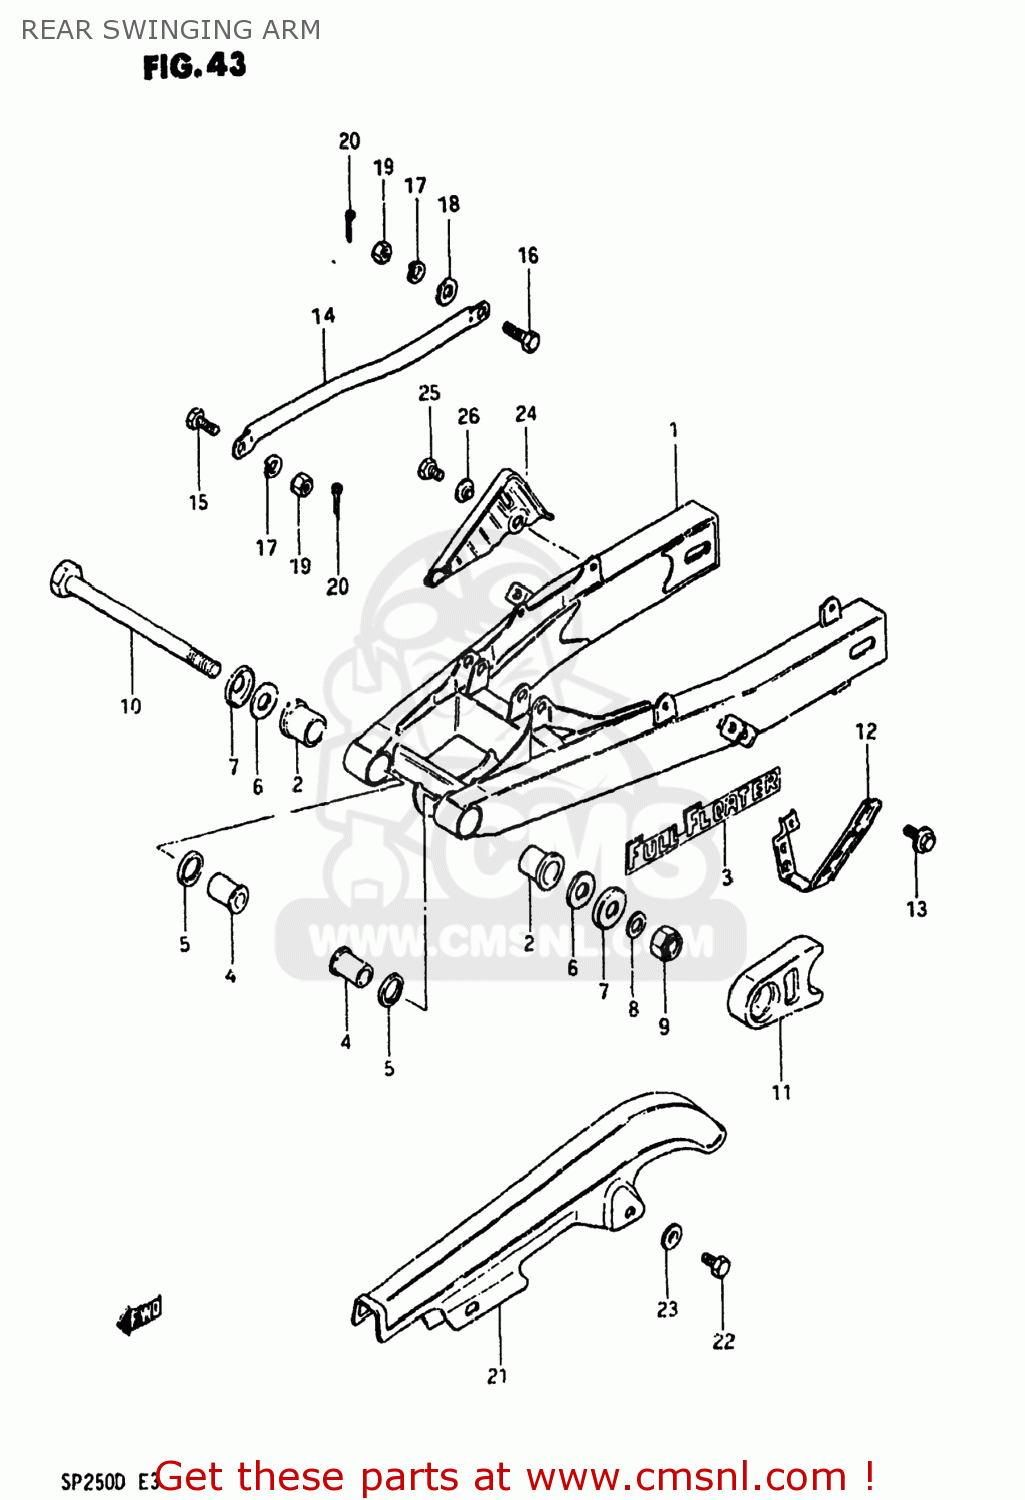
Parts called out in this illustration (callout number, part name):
1	SWINGING ARM, REAR
2	BUSHING,RR SWGARM PIVOT
3	EMBLEM
4	SPACER,RR SWGARM PIVOT OUTER
5	SEAL,OIL(20X27X5)
6	WASHER
7	COVER,REAR SWING ARM DUST
8	WASHER
9	NUT 14MM
10	SHAFT,REAR SWING ARM
11	BUFFER,CHAIN TOUCH DEFLECTOR
12	GUIDE,CHAIN
13	BOLT 8X12
14	LINK,REAR TORQUE
15	BOLT(8X22.5)
16	BOLT(8X26.5)
17	LOCK WASHER
18	WASHER
19	NUT
20	PIN 20X20
21	CASE,CHAIN
22	BOLT 6X8
23	WASHER
24	GUARD,PILLION FOOT
25	BOLT 6X8
26	WASHER
